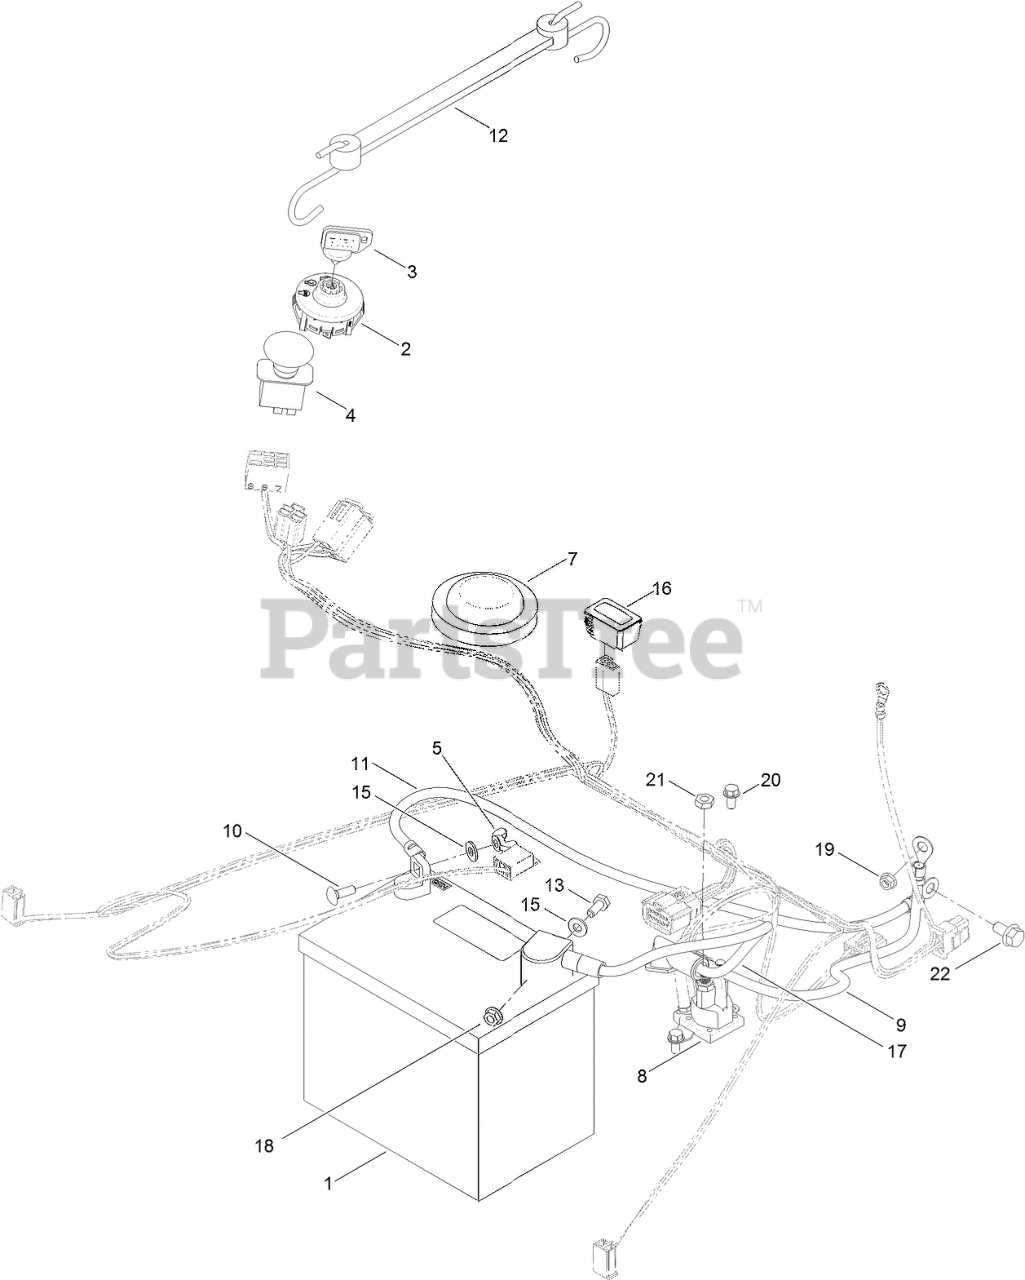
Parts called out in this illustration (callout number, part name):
1	BATTERY
2	SWITCH-IGNITION
3	KEY-IGNITION
4	SWITCH-PTO
5	NUT-WING
7	SWITCH-SEAT
8	SOLENOID
9	CABLE-BATTERY, POSITIVE
10	BOLT-CARR
11	CABLE-BATTERY, BLACK
12	HOLDDOWN-BATTERY
13	SCREW-HH
15	WASHER-FLAT
16	HOURMETER
17	CABLE-BATTERY, RED
18	NUT-HF
19	NUT-HF
20	SCREW-HWH
21	NUT-JAM
22	SCREW-HHF
